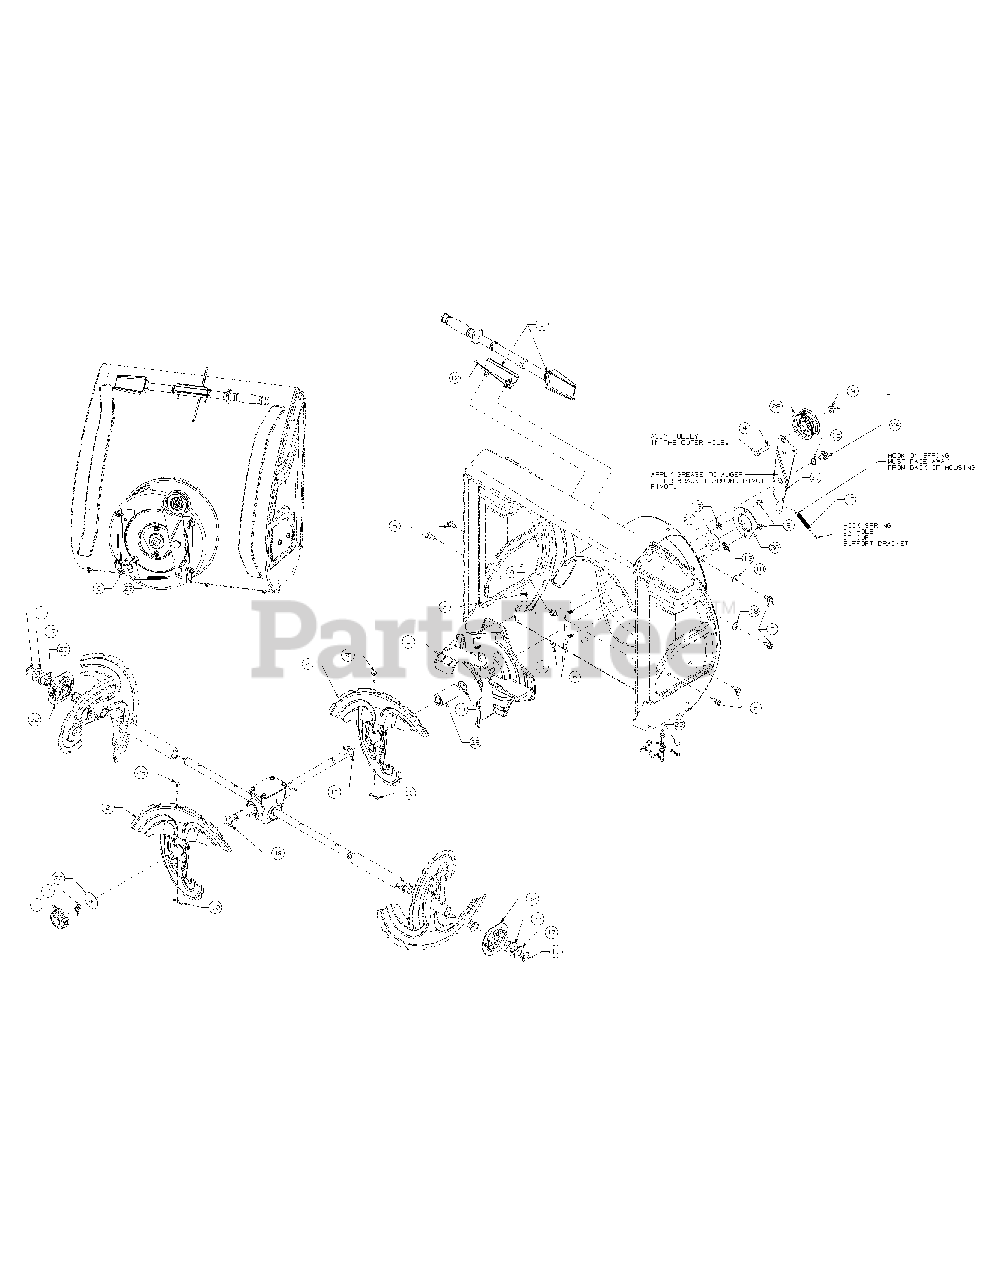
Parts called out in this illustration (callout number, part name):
1	Clip-Tool Mtg
1	Tool-Cleanout
4	Screw-Hex 3/8-16 X
5	SCREW 5/16-18 x .750
6	Carriage Bolt 5/16-18 X .75
7	Screw-Tap 5/16-18X
8	Nut-Flglk 5/16-18
9	Nut-Flange Lk.Nylo
10	Pin-Cotter
11	Ring-E
12	Tie-Cable 7"
13	Nut-Push On
15	Spring-Extension .
16	Washer-Wave .660 I
17	Washer-Fl-.760Id X
18	Washer-Bell .337 X
19	Washer-Fl .793 I
20	Washer-Hub Cap .40
21	Grease
22	Grease
23	SHOULDER SCREW .498 DIA x .340
24	Screw-Shld .625
25	Pin-Shear .25
26	Flange Bearing .
27	Bearing-Flange Hex
28	Spacer
29	Pulley:Idler:Flat
30	Housing-Bearing
